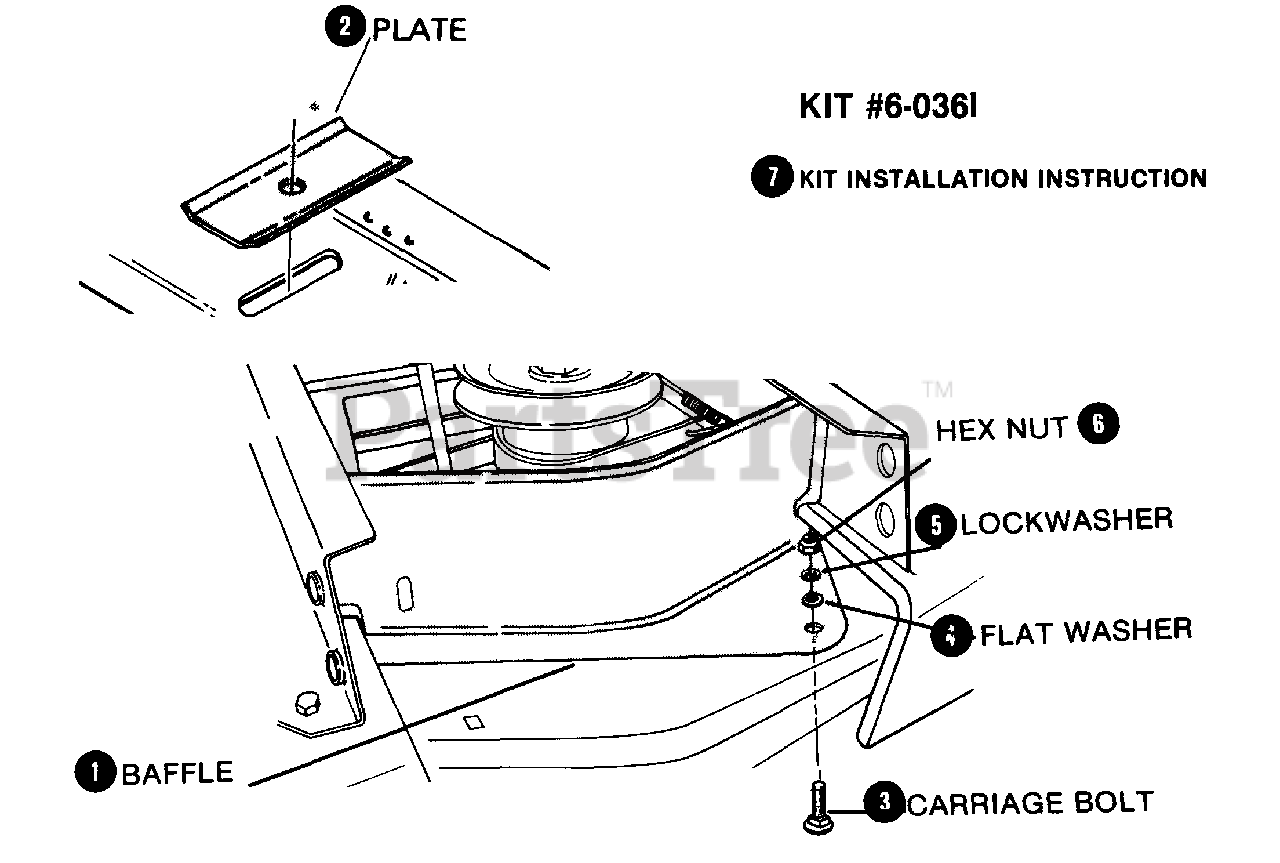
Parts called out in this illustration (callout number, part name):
1	BAFFLE, Deck
2	PLATE, Idler (Adjusting Slot)
3	BOLT, 3/8C x 3/4 Carriage
4	WASHER, 3/8 SAE (Flat)
5	LOCKWASHER, 3/8 Split
6	NUT, 3/8C Hex
7	INSTRUCTION, Kit Installation
60361	Deck Baffle Kit
